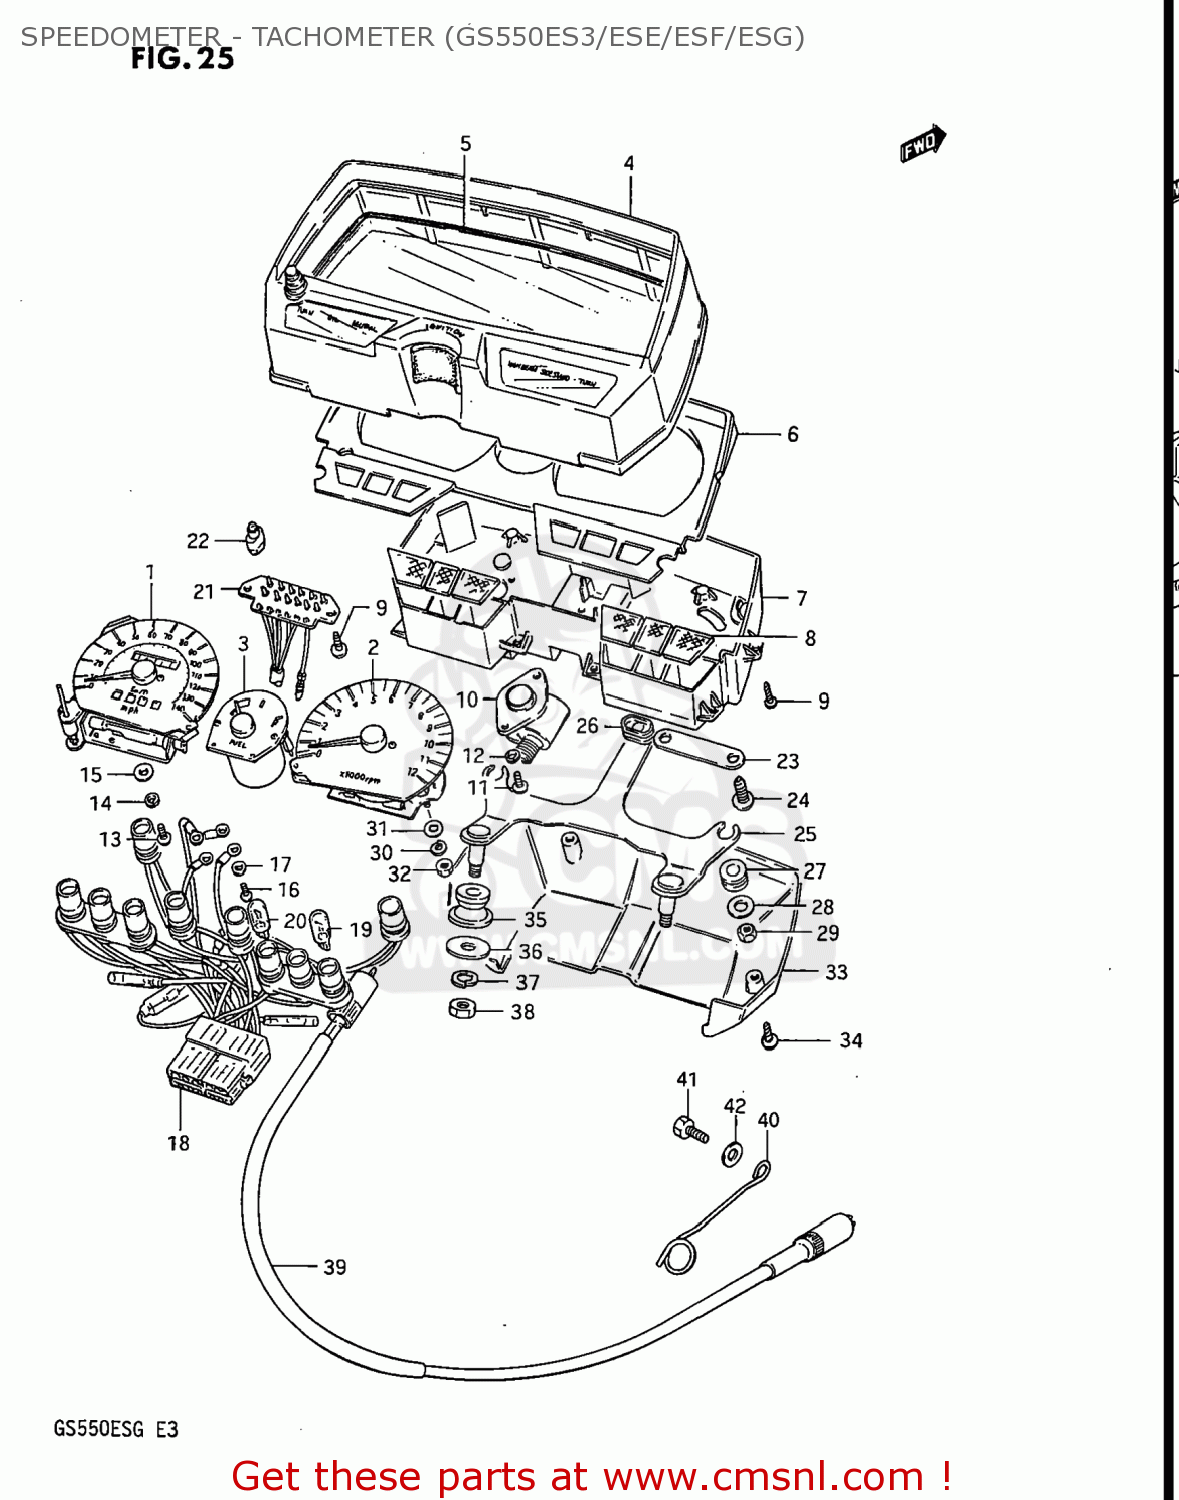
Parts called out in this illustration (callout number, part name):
1	SPEEDOMETER
2	TACHOMETER
3	METER,FUEL
4	HOOD,METER
5	GLASS,SPEEDOMETER
6	PLATE,METER WINDOW
7	CASE,METER,INNER
8	LENS SET,PILOT
9	SCREW,GEAR INDICATOR
10	BOX,GEAR
11	SCREW 4X10
12	WASHER,LOCK 4M
13	SCREW
14	LOCK WASHER
15	WASHER
16	SCREW
17	WASHER
18	SOCKET,METER
19	BULB(12V3.4W,T10,BF175-01450A)
20	BULB(12V1.7W,T10,WB121)
21	SOCKET,GEAR INDICATOR
22	BULB(14V1.12W)
23	PLATE,COUPLER
24	SCREW
25	BRACKET,METER
26	CUSHION,METER
27	CUSHION,METER
28	WASHER,METER
29	NUT
30	WASHER,LOCK 4M
31	WASHER,SPEEDOMETER
32	NUT
33	COVER,METER,UNDER
34	SCREW
35	CUSHION,METER BRACKET
36	WASHER (8.5X20X1.6)
37	WASHER,LOCK,8.
38	NUT
39	CABLE ASSY,SPEEDOMETER
40	CLAMP,SPEEDOMETER CABLE
41	BOLT, UPPER
42	WASHER
